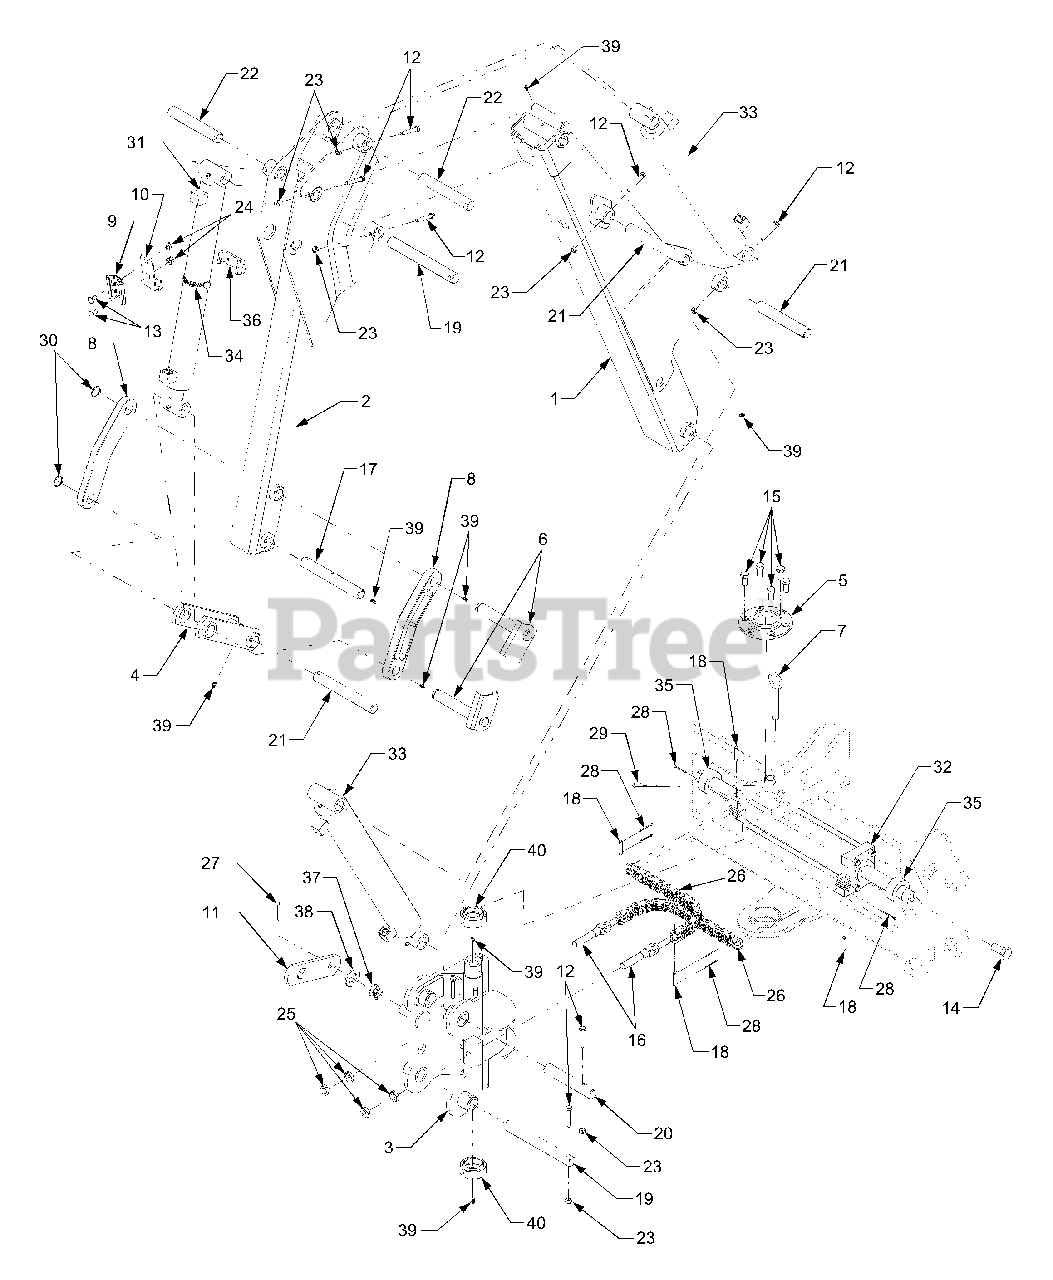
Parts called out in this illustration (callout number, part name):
1	Boom Assembly, Backhoe
2	Arm Assembly, Dipper
3	Pivot, Boom
4	Crank, Bucket
5	Cap, Bearing
6	Pin Assembly. Wrist
7	Pin, Boom Swing Lock
8	Link, Bucket Guide
9	Bracket, SMV Female
10	Bracket, SMV Mounting
11	Plate, Boom Lock
12	Screw, Hex Cap, M8-1.25 x 50 Hardened
13	Screw, Carriage, M8-1.25 x 16
14	Screw, Hex Cap, M20-2.5 x 40
15	Screw, Hex Cap, M12-1.5 x 25 GR8.8
16	Pin, Chain Adjustment
17	Pin, Wrist
18	Pin, Chain Clevis
19	Pin, Wrist - Boom Pivot
20	Pin, Wrist - Boom Cylinder
21	Pin, Wrist
22	Pin, Wrist - Dipper Pivot
23	Nut, Hex Nylon Lock, M8-1.25
24	Nut, Hex Flange Lock, M8-1.25
25	Nut, Hex Jam, M16-2.0
26	Chain, Boom Swing
27	Pin, Cotter, 3/16 x 1.5
28	Pin, Cotter, 1/8 x 1.25
29	Pin, Internal Cotter
30	Ring, Retaining, 25mm
31	Cylinder, Bucket
32	Cylinder, Boom Angle
33	Cylinder, Boom
34	Clamp, Hose
35	Bumper, Swing Cylinder
36	Clamp, Hose
37	Spring, Compression
38	Washer, Special
39	Fitting, Lube
40	Bearing, Spherical, 62mm x 40mm
